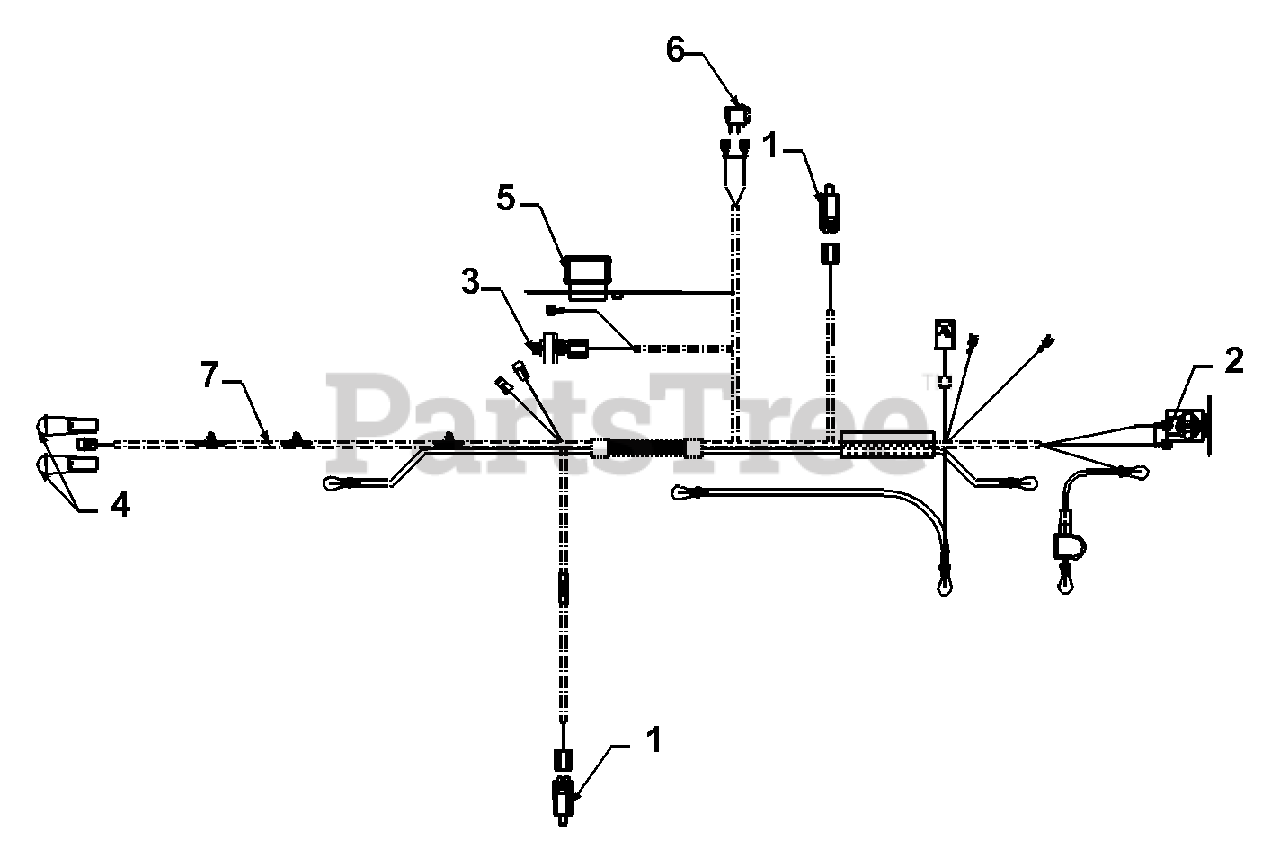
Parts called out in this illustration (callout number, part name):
1	Safety Switch
2	Solenoid
3	Ignition Switch
4	Bulb (Headlight)
5	Ammeter
6	Light Switch
7	Wire Harness w/Lt./Amp./Sw.
